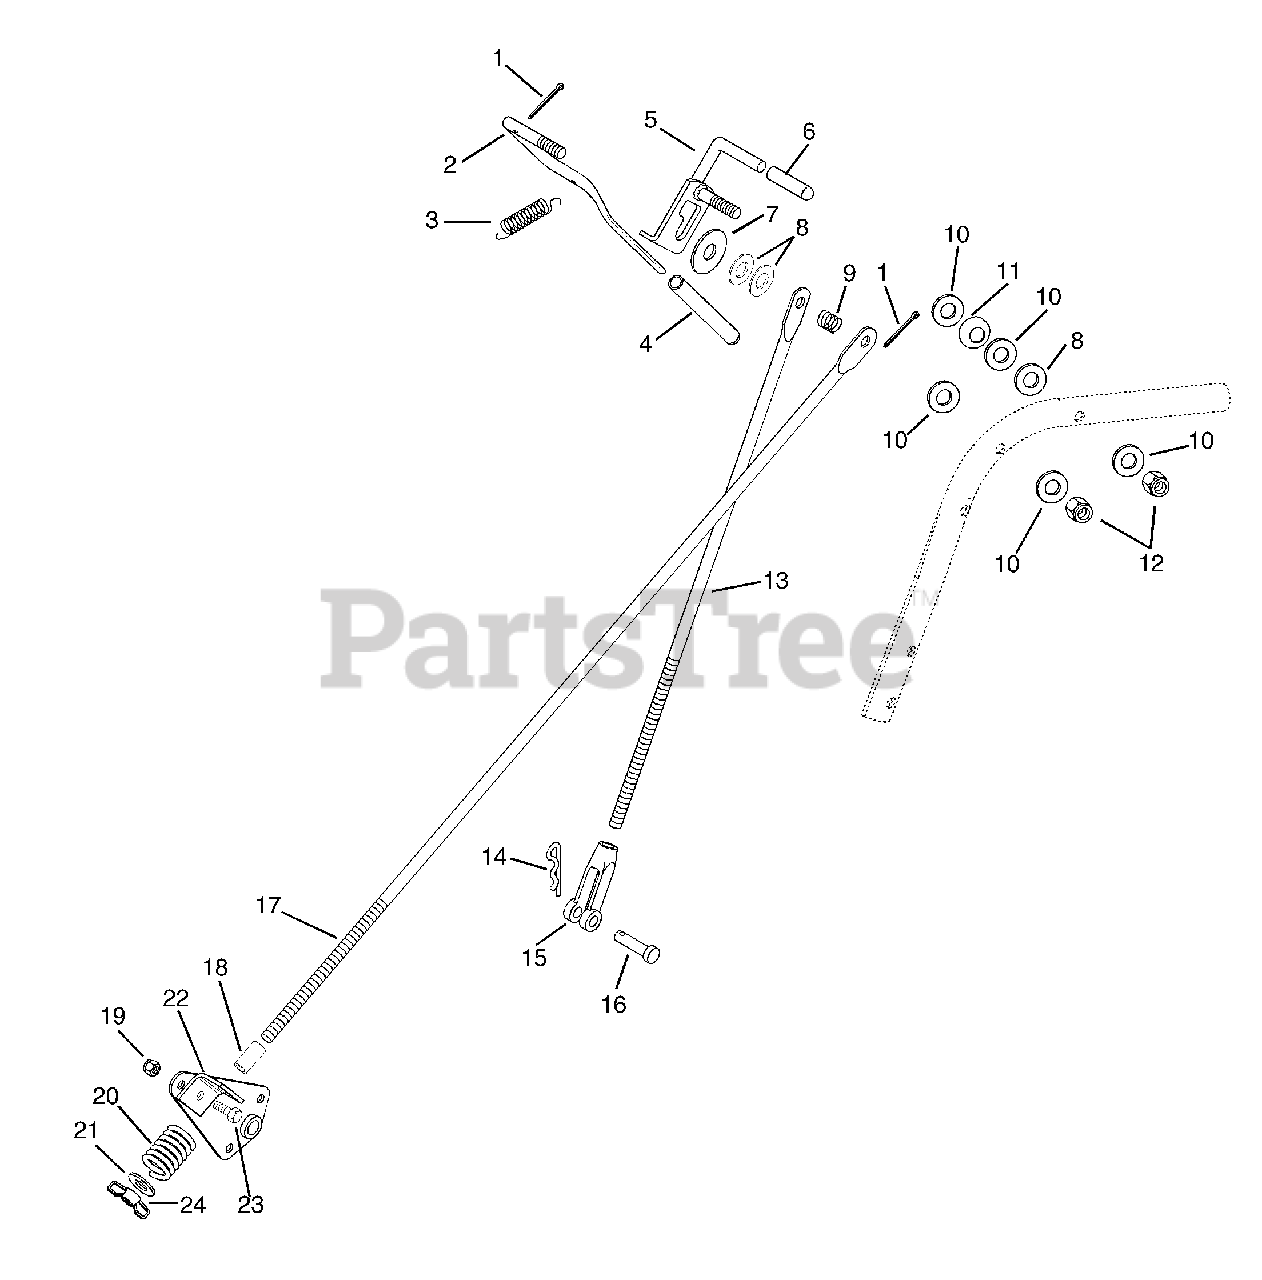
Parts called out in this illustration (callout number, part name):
1	Pin-Cotter .09 x .75
2	Lever, Hand Control
3	Spring-Tension .041 x .500 x 1.750
4	Grip, Hand Clutch Lever
5	Weldment, Clutch-Brake Lock
6	Tip-Brake Lock Lever
7	Washer-Flat-Steel .438 x 1.375 x .083
8	Washer-Flat-Steel .406 x .812 x .065
9	Spring-Compression .045 x .600 x .750
10	Washer-Flat-Nylon .375 x .75 x .060
11	Washer-Spring .375
12	Nut-Locking-Center .38-16
13	Rod, Clutch Actuating
14	Pin-Hair-Internal .08 x .18 x 1.18
15	Yoke .31-24 x 2.250
16	Pin, Clevis 5/16 x .812
17	Rod, Brake
18	Bushing .327 x .411 x 2.0
19	Nut-Locking-Center .25-20
20	Spring-Compression .125 x .78 x 1.00
21	Washer-Flat-Steel .344 x .688 x .065
22	Bracket, Brake Rod
23	Bolt-Hex .25-20 x .75 Grade 5
24	Nut-Nylock-Wing .312-18
